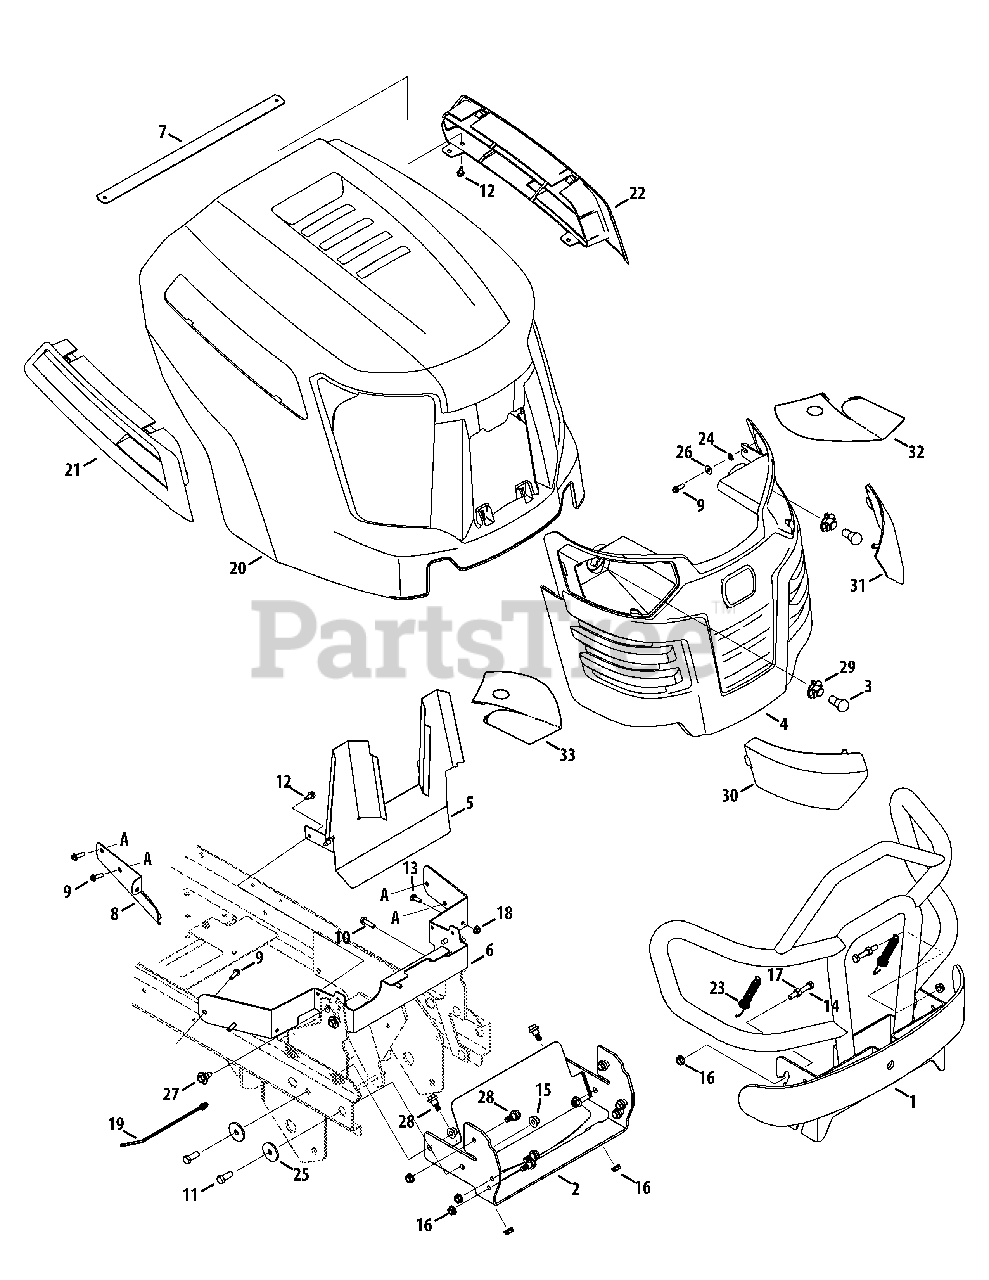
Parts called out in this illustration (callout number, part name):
1	Front Bumper Assembly
2	Brush Guard Assembly
5	Heat Shield
6	Hood Pivot Bracket
8	Heat Shield
9	Hex Washer Screw, 1/4 x .750
10	Hex Washer Screw, 5/16-14 x 1.00
11	Hex Screw, 3/8-16 x 1.00
12	Hex Washer Screw, 1/4-20 x 0.500
13	Hex Cap Screw, 1/4-20 x .620
14	Hex Cap Screw, 5/16-18 x 2.00
15	Flange Lock Nut, 3/8-16
16	Flange Lock Nut, 5/16-18
17	Hex Nut, 5/16-18
18	Hex Flange Nut, 1/4-20
19	Cable Tie, 7.5
20	Hood
21	RH Hood Scoop
22	LH Hood Scoop
23	Extension Spring, .54 OD X 5.0 LG
24	Lock Washer, 1/4
25	Flat Washer, .390 x 1.500 x .134
26	Flat Washer, .271 x .630 x .065
27	Shoulder Screw, 5/16-18 x .43 x .29
28	Shoulder Bolt, .435 x .350, 5/16-18
29	Lamp Socket
30	RH Hood Lens
31	LH Hood Lens
32	Left Lens Reflector Label
33	Right Lens Reflector Label
